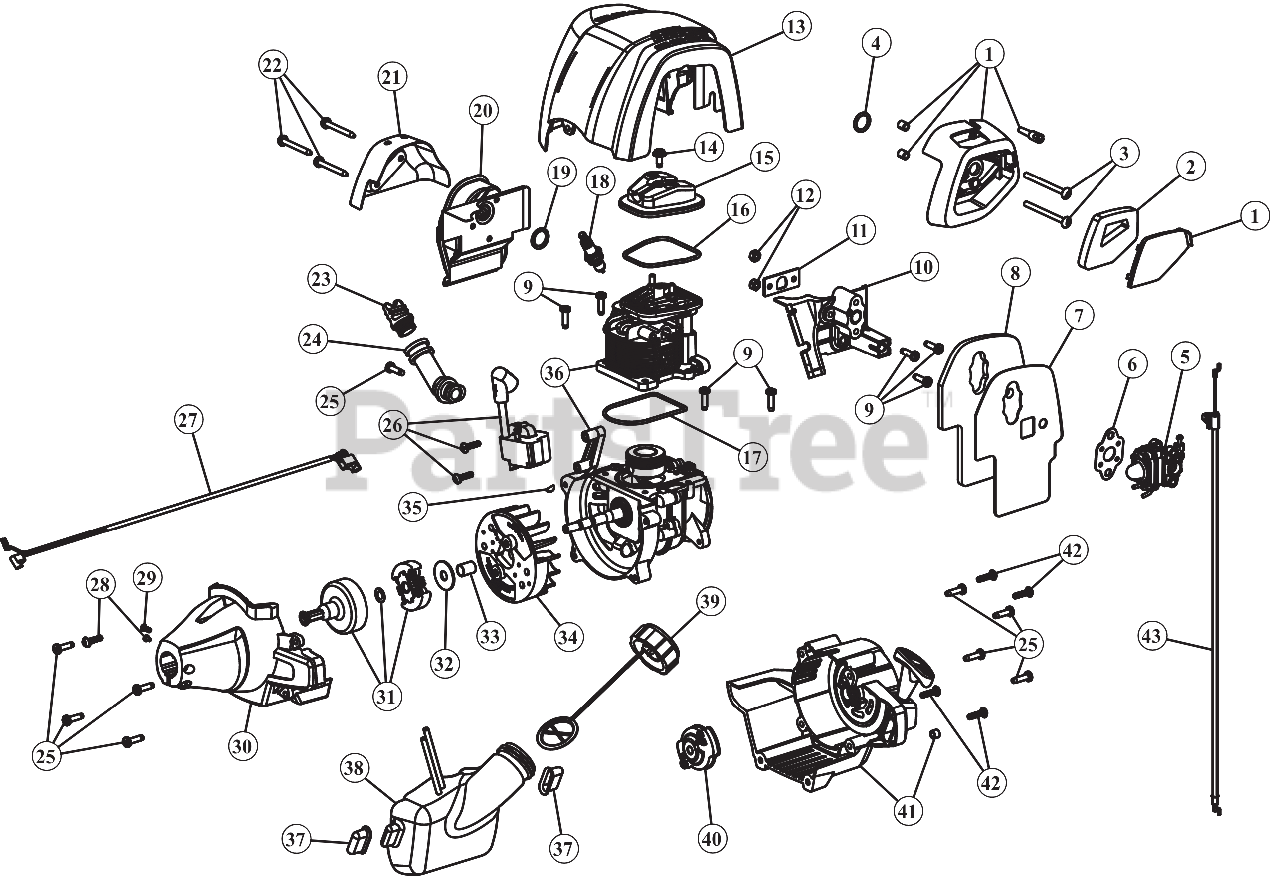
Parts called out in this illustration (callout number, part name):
1	AIR CLEANER ASSEMBLY
2	AIR FILTER
3	SCREW 10-32X3
5	CARBURETOR ASSEMBLY
6	CARBURETOR GASKET
7	CARBURETOR GASKET
8	HEAT SHLD CARB AC5
9	SCREW, M5 x 18.7MM
11	INSULATOR GASKET
13	ENGINE COVER TOP
14	SCR, VALVE COVER
15	ROCKER COVER
17	O-RING CYL AC5
18	SPARK PLUG 10MM:EM
19	GASKET/MUFFLER
20	MUFFLER ASSEMBLY AC5.1
21	MUFFLER SHLD
22	SCREW M5 x 44MM
23	OIL PLUG ASSEMBLY
24	OIL FILL TUBE
25	SCREW M5-0.8 x 19
26	MODULE ASSEMBLY INT
27	WIRE LEAD W/SUPPR
28	SCREW:CLMPNG W/NUT
29	SCREW, 8-32 x .312 P
30	CLUTCH COVER
31	SMALL CLUTCH ASSEMBLY W/SMALL DRUM
32	WASH, CLUTCH O.D. 1.155 +/- .0
33	SPACER .591"
34	FLYWHEEL W/KEY
35	WOODRUFF KEY #403-.125 x .375
36	SHORT BLOCK
37	FUEL TANK PADS
38	FUEL TANK ASSEMBLY
39	FUEL CAP ASSEMBLY
40	PAWL ASSEMBLY AC5
41	STARTER HOUSING ASSEMBLY
42	SCREW 8-16 x 3/4
43	THROTTLE CABLE
